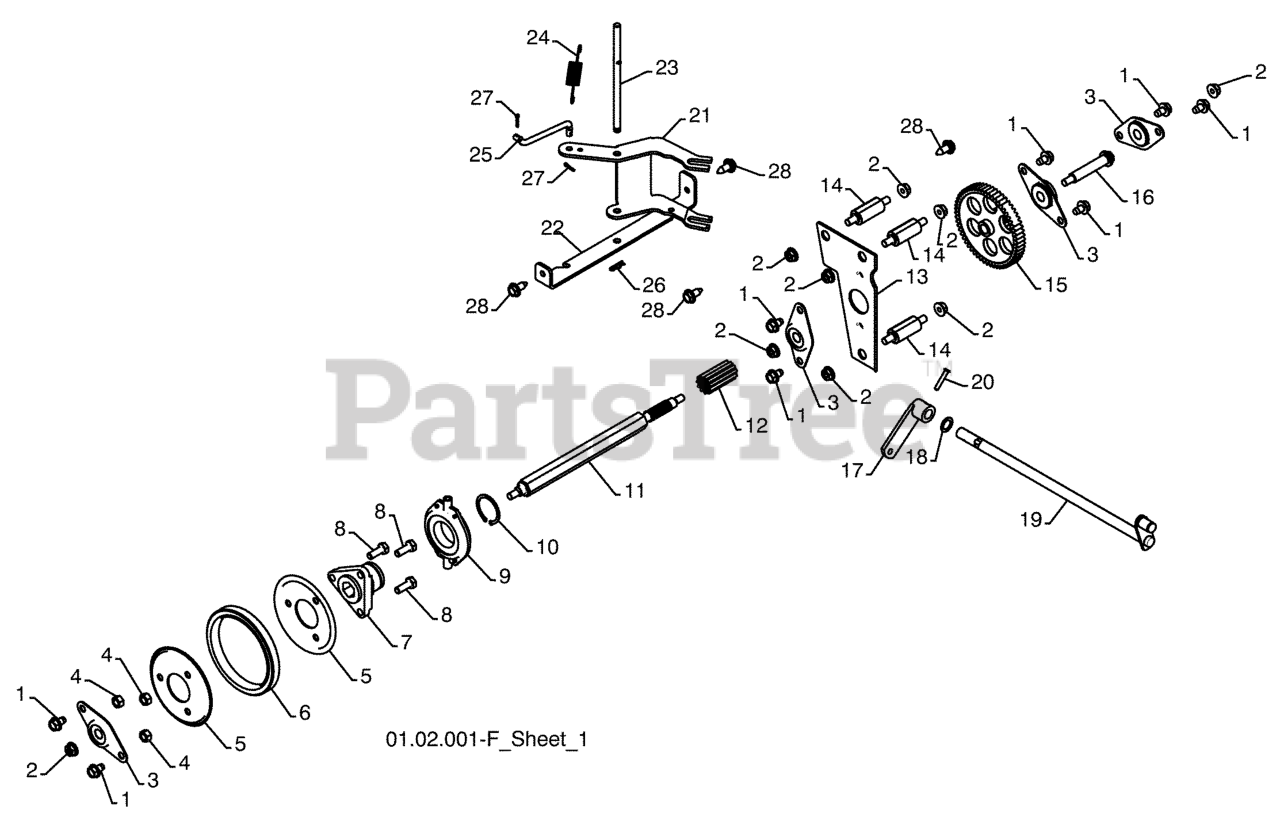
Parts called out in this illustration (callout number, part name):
1	BOLT 5/16-18 X .500
2	NUT.LOCK.5/16-18
3	BEARING, FLANGE
4	NUT.CENTERLOCK.5/16-
5	PLATE.RUBBER.WHEEL
6	RING, RUBBER WHEEL
7	HUB, RUBBER WHEEL
8	BOLT
9	TRUNNION BEARING ASSY
10	RETAINING RING (2 2)(3 2)
11	SHAFT.HEX.LONG
12	GEAR, PINION
13	AUXILLARY PLATE
14	SPACER, PLATE
15	GEAR, INTERMEDIATE
16	SHAFT, AUXILIARY
17	ARM, AUGER CONTROL
18	THRUST WASHER
19	SHAFT, AUGER CONTROL
20	CLEVIS PIN
21	LEVER, SPEED CONTROL
22	BRACKET, PIVOT, SHIFT
23	PIN, PIVOT
24	SPRING, BIAS
25	LINK, SPEED CONTROL
26	RETAINER CLIP PM
27	RETAINER CLIP
28	SCREW
